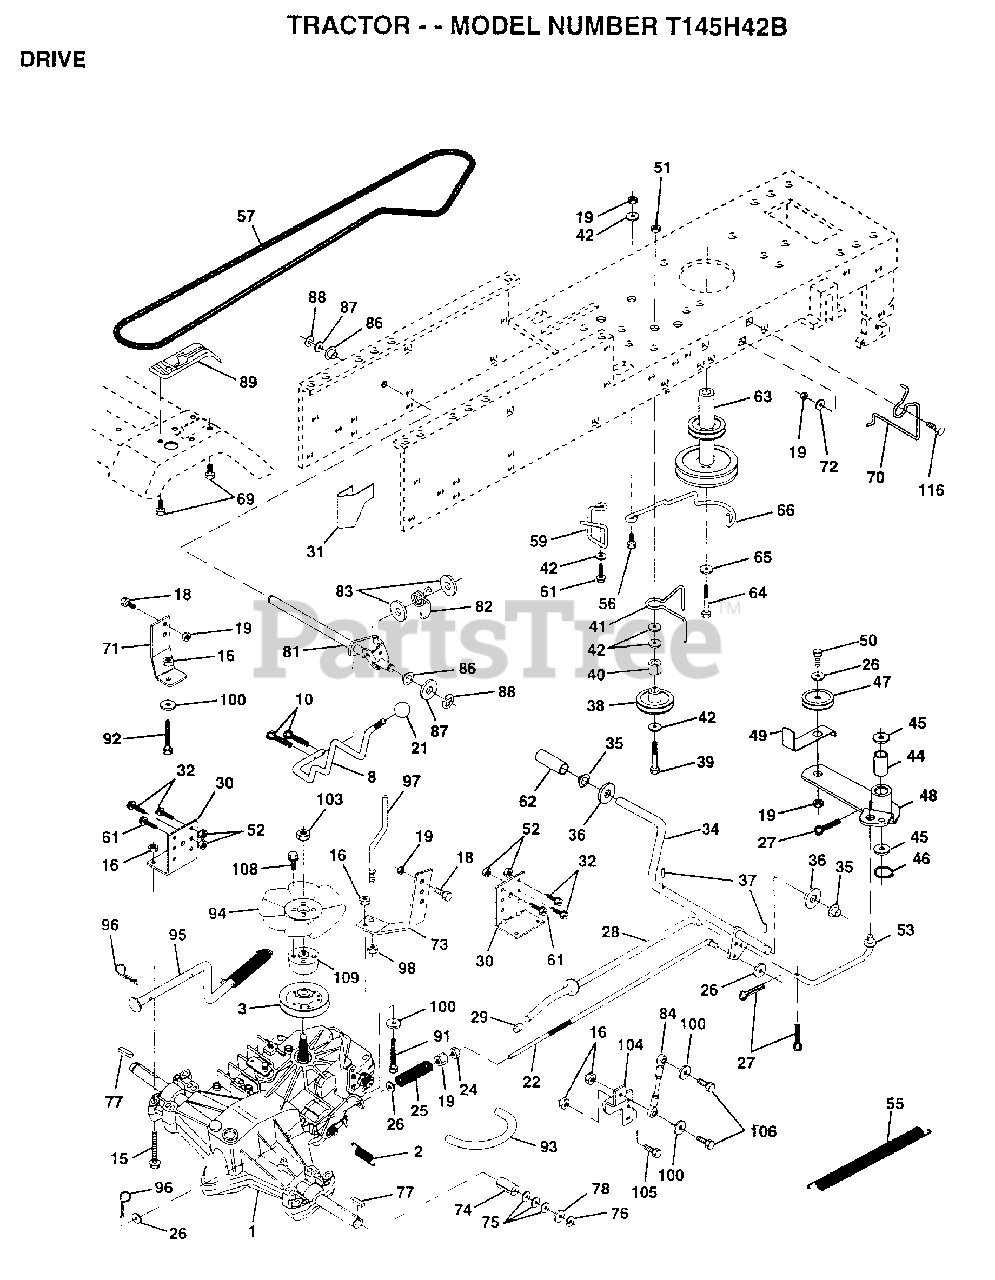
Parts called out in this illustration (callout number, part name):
1	TRANSAXLE HYD 0319-0500
2	SPRING RET BRAKE
3	PULLEY.4.20.HYDRO
8	ROD SHIFT FEND LT
10	PIN COTTER 1/8
15	BOLT.HX.FLG.5/16
16	NUT
18	BOLT
19	NUT
21	KNOB DLX BLK/BLK
22	ROD.BRAKE.HYDRO.
24	NUT
25	SPRING ROD LT
26	WASHER
27	COTTER PIN
28	ROD.BRAKE.PARK.LT
30	TRANSAXLE MTG BKT
31	"KEEPER,BELT LH T"
32	BOLT
34	SHAFT FOOT PEDAL
35	NYLON BEARING
36	WASHER LT
38	PULLEY.IDLER.FLAT
39	BOLT
40	SPACER T
41	KEEPER BELT
42	WASHER
44	"LY, BEARING"
45	WASHER LT
46	KLIP RING
48	ARM IDLER
49	RETAIN BELT
53	"LINK, CLUTCH T"
55	"SPRING, RETURN LT"
57	BELT-V.HYDR.84.61
59	KEEPER BELT CNTSP
61	SCREW
62	PEDAL COVER T
63	PULLEY.ENGINE
64	BOLT
65	LOCKWASHER
69	SCREW HEXWSH H-L
70	KEEPER BELT ENG
71	STRAP.TORQ.LH.HYD
72	WASHER
73	STRAP.TORQ.RH.HYD
74	SPACER SPLIT
75	WASHER
76	E-RING LT
77	SQUARE KEY
78	WASHER
81	SHAFT.CROSS.HYD
82	"SPRING,TORSION"
83	WASHER
84	ROD.TIE.BALL.HYD.
86	BUSHING
87	WASHER D
88	KLIP RING
92	HEX BOLT
93	"LINE FUEL HYD 4"""
94	"FAN 7"" HYDRO"
96	RETAINER M
97	KEEPER.BELT.RH.HY
98	NUT
100	WASHER M
104	ARM.CONTROL.PUMP
105	SCREW CAP 5/16-18
106	BOLT
108	SCREW.HXHD.10-20
109	ADAPTOR.FAN.HYDRO
116	BOLT RDHD 3/8-16
